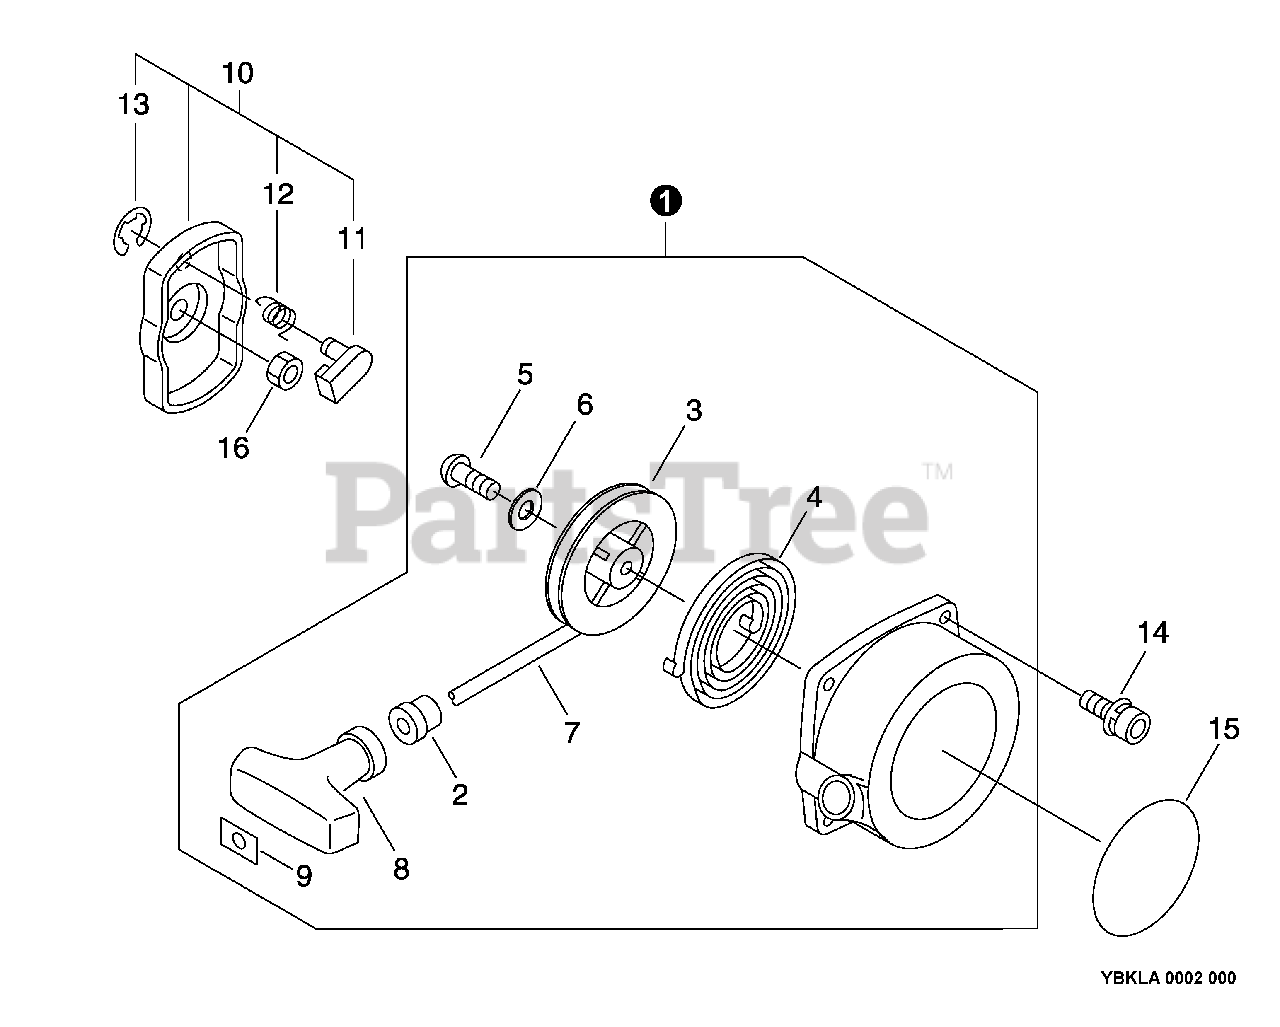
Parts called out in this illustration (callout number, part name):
1	STARTER ASSY, RECOIL
2	GUIDE, ROPE
3	REEL, ROPE
4	SPRING, RECOIL
7	ROPE, STARTER 4.0×880
8	GRIP, STARTER
9	RETAINER, ROPE
10	PULLEY ASSY, STARTER
11	PAWL, STARTER
12	SPRING, RETURN
13	E-RING 4
14	BOLT 4×20
15	LABEL, ECHO
16	NUT 8×1.25
